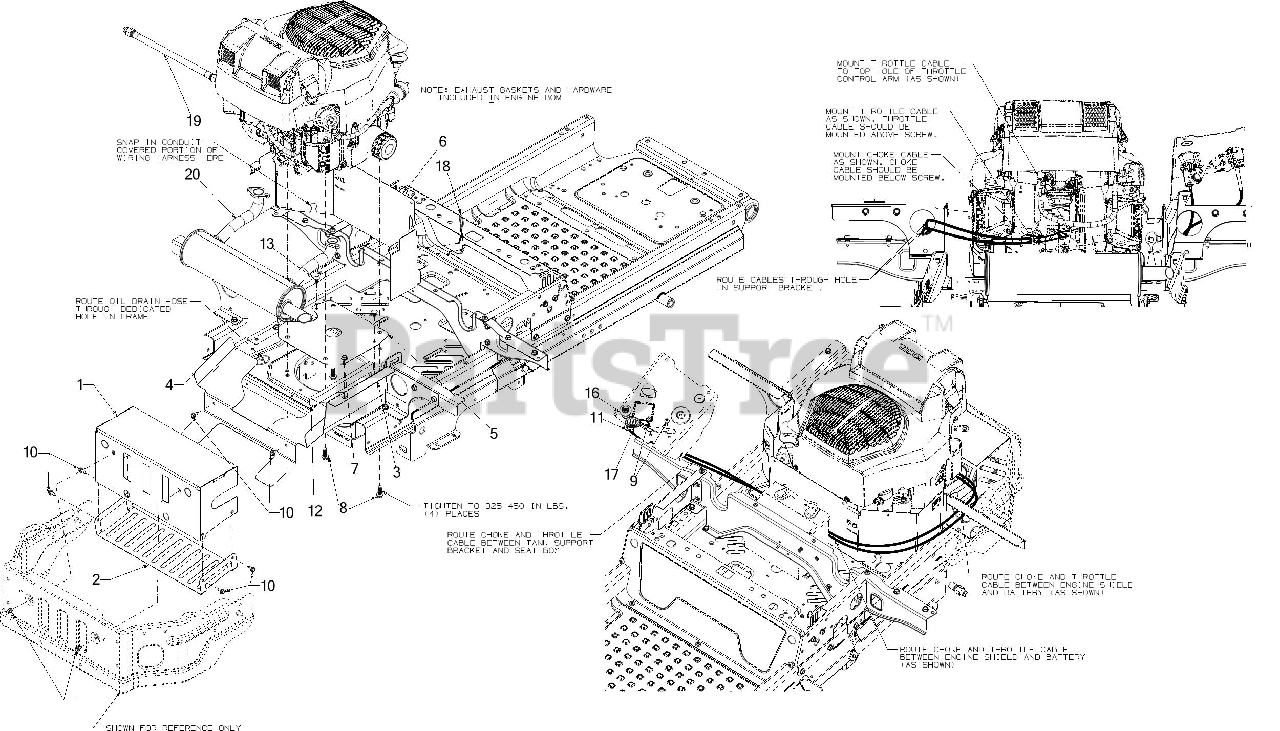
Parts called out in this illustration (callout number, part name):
1	MUFFLER SHIELD BRACKET
2	LOWER MUFFLER BRACKET
3	POD SHIELD BRACKET (RH)
4	MUFFLER BRACKET
5	ENGINE SHIELD PLATE
6	ENGINE SHIELD BRACKET
7	SCREW 5/16-18 x .750
8	SCREW 3/8-16 x 1
9	SCREW 1/4-20 x .5
10	SCREW 1/4-20X.625
11	HEX FLANGE NUT
12	FOAM-TAPE 1.00 x .500 x 9.375
13	RATCHET CLIP .250
16	61" CHOKE CABLE
17	THROTTLE CABLE 59"
18	TANK SUPPORT ROD
19	OIL DRAIN HOSE
20	ROUND MUFFLER
